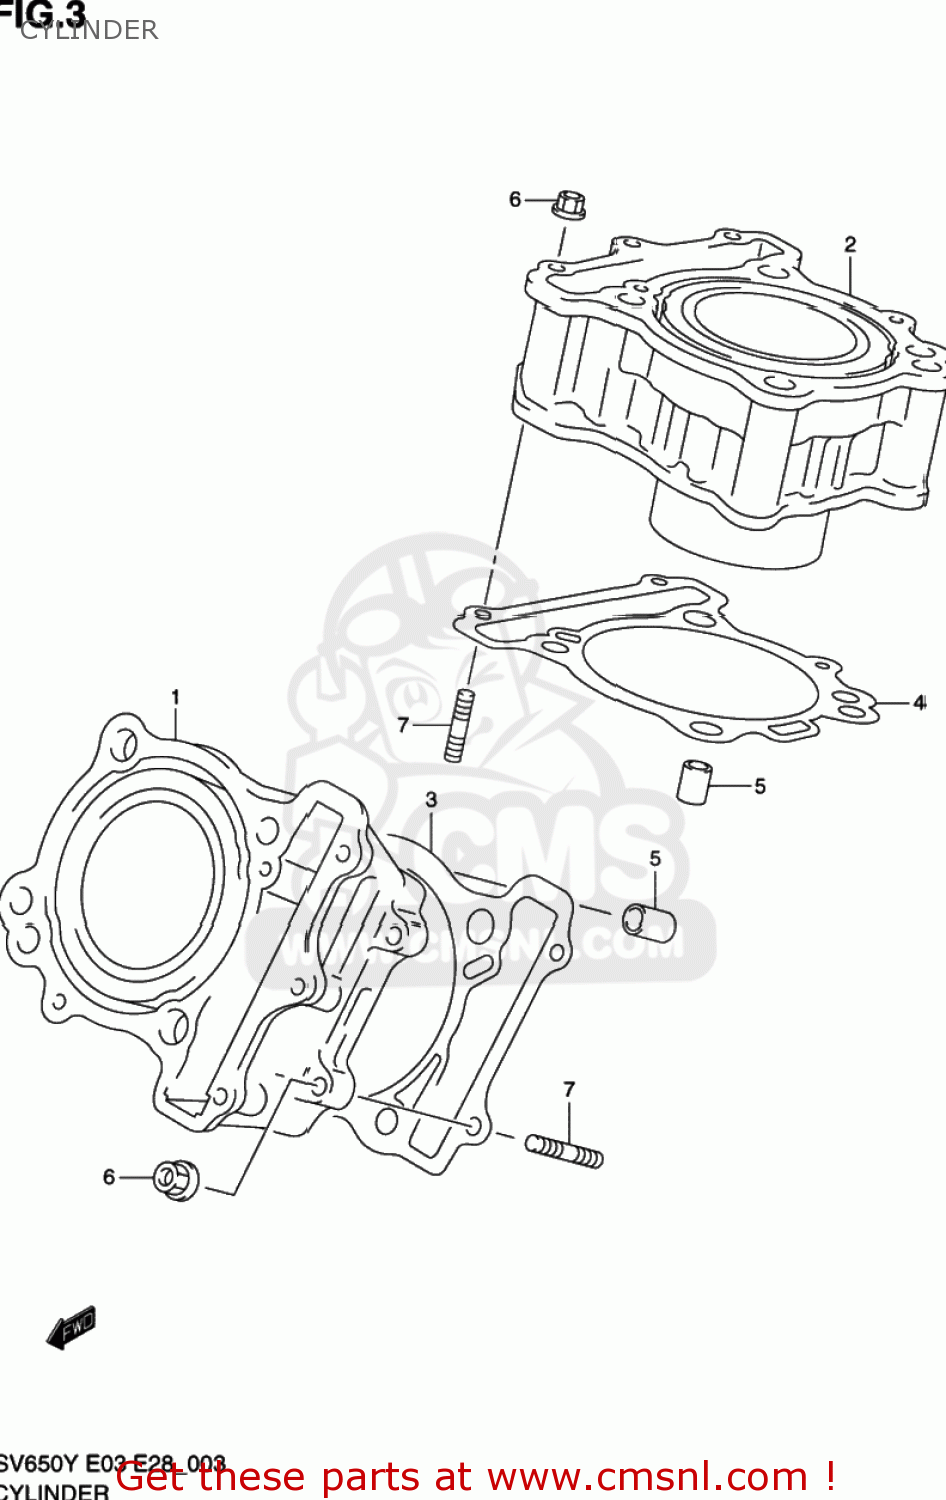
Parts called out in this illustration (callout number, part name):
1	CYLINDER,FR
2	CYLINDER,RR
3	GASKET,CYLINDER FR (NAS)
4	GASKET,CYLINDER RR (NAS)
5	PIN
6	NUT
7	STUD BOLT
